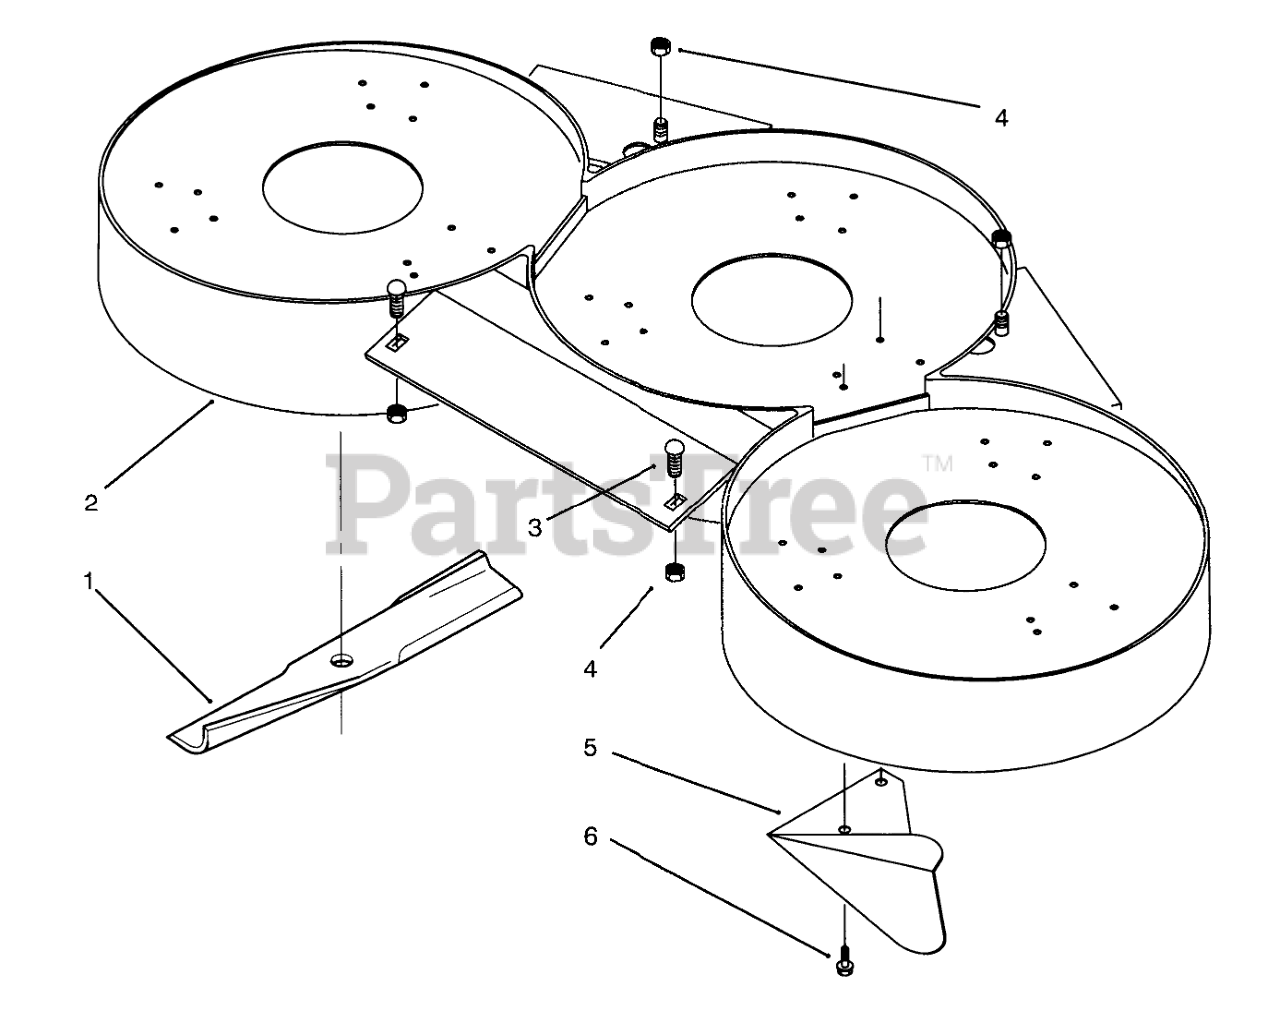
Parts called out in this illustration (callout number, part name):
1	BLADE KIT (3- 79-2920)
2	Baffle
3	BOLT-CARR
4	NUT-LOCK, NI
5	Kicker
6	SCREW-HWH
